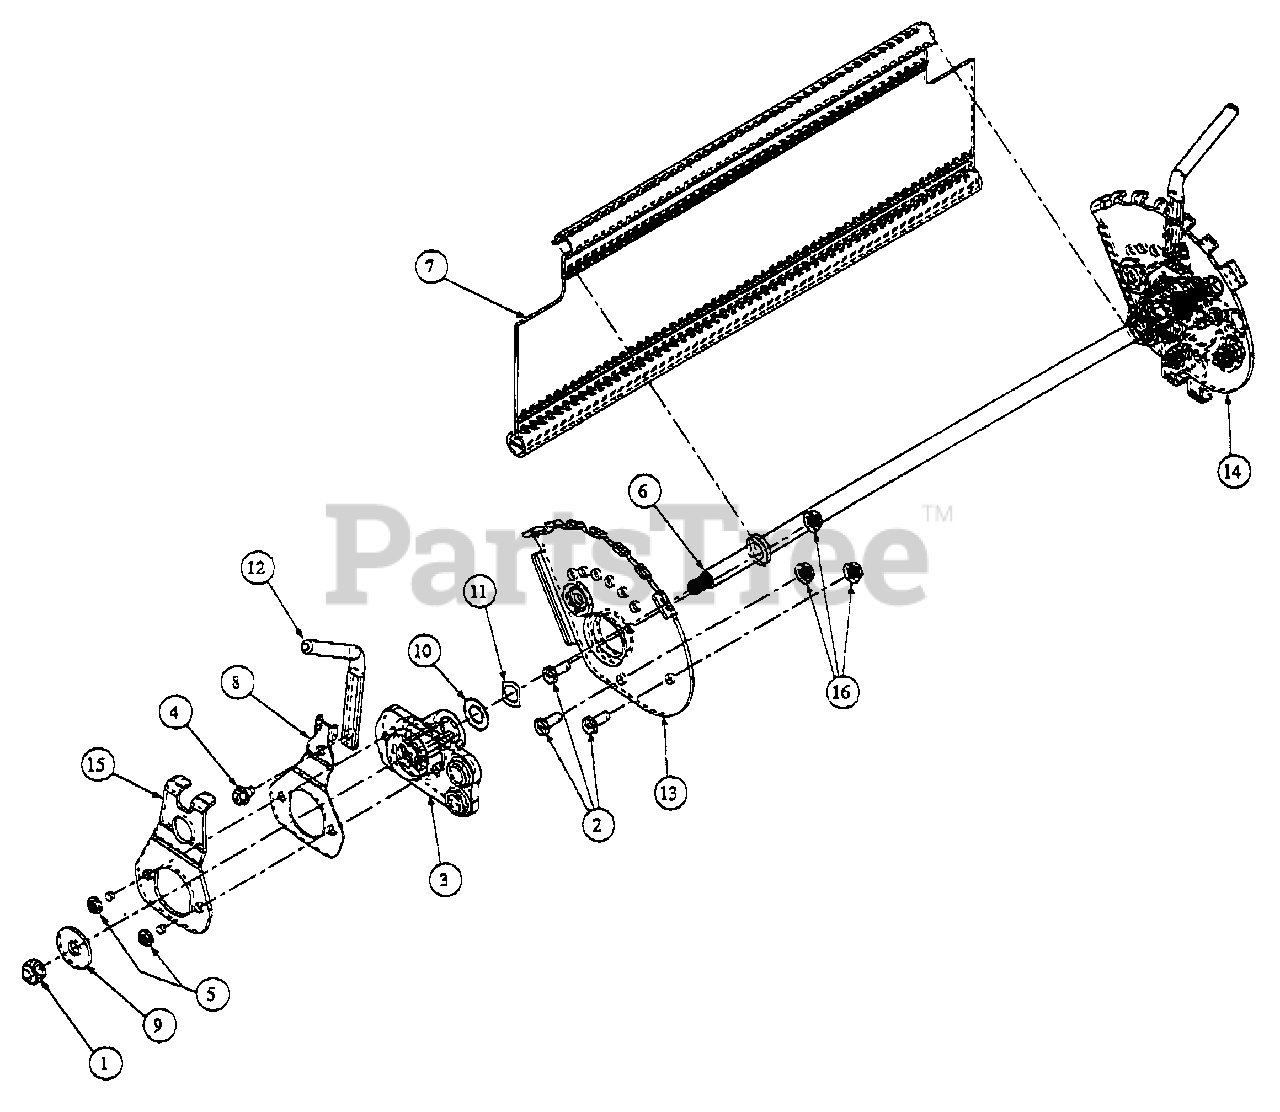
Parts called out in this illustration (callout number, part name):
1	L-Nut, 3/8-16, NYL INS. GR A.
2	HHCS, 1/4-20, .620, GR5, Standard
3	Pivot Wheel Bracket Assembly, 2 POS
4	Screw, TT, 1/4-20, 0.375, Hex Index Washer
5	Screw, TT, 1/4-20, 0.625, PANTRXI
6	Rear Axle
7	Trail Shield
8	Spring Plate Height Adjuster
9	Flat Washer, .411 x 1.25 x .100
10	Flat Washer, .536 ID X .781 OD X .01
11	Wave Washer, .536 ID X .930 OD X .05
12	Height Adjustment Handle
13	Height Adjustment Bracket, Right Rear
14	Height Adjustment Bracket, Left Rear
15	Spring Lever Support Bracket
16	Nut, 1/4-20, Hex Flange, Lock, Group F
